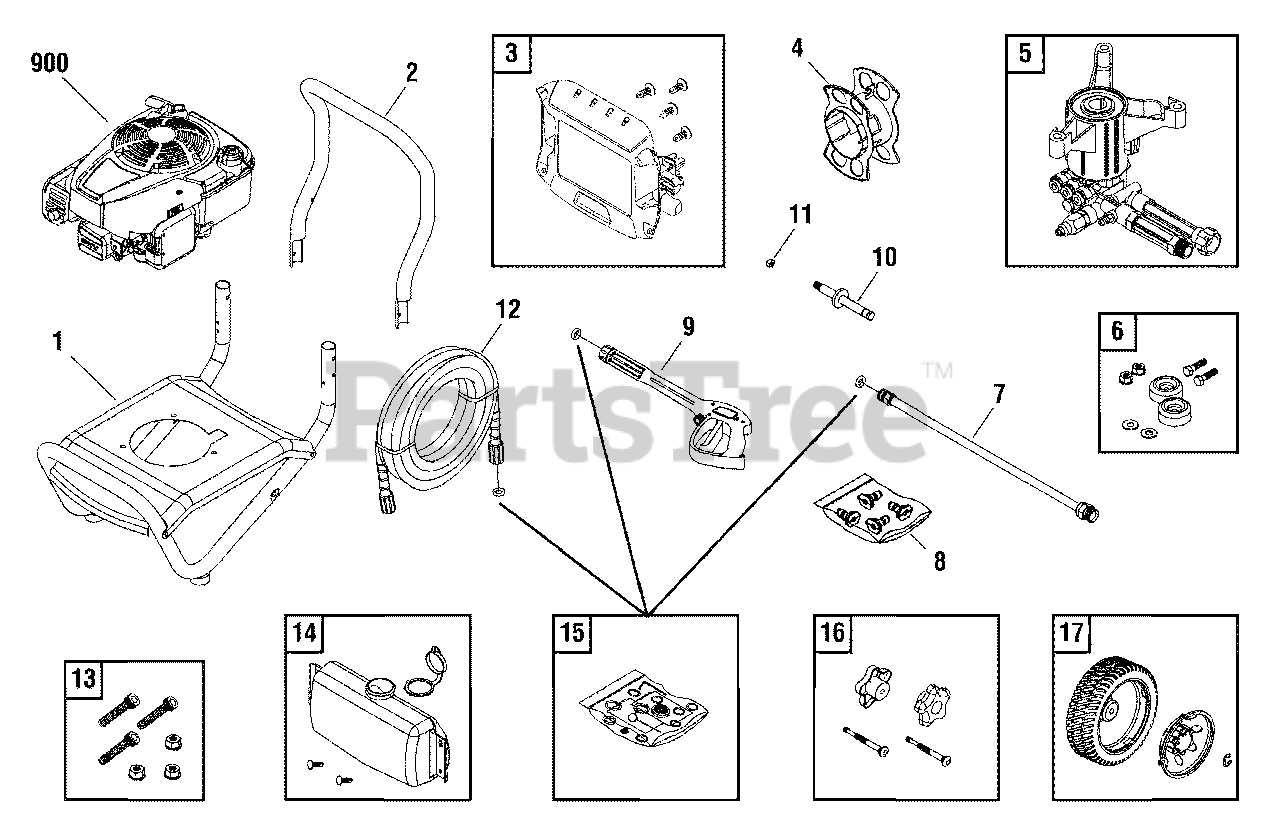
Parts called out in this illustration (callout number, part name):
5	PUMP
6	MOUNT, Vibration
7	EXTENSION, QC
8	KIT, QC Nozzles
9	GUN
11	NUT
12	HOSE
13	KIT, Hardware, Pump Mounting
15	KIT, O-Rings
16	KIT, Hardware, Handle
17	KIT, Wheel
900	* ENGINE
